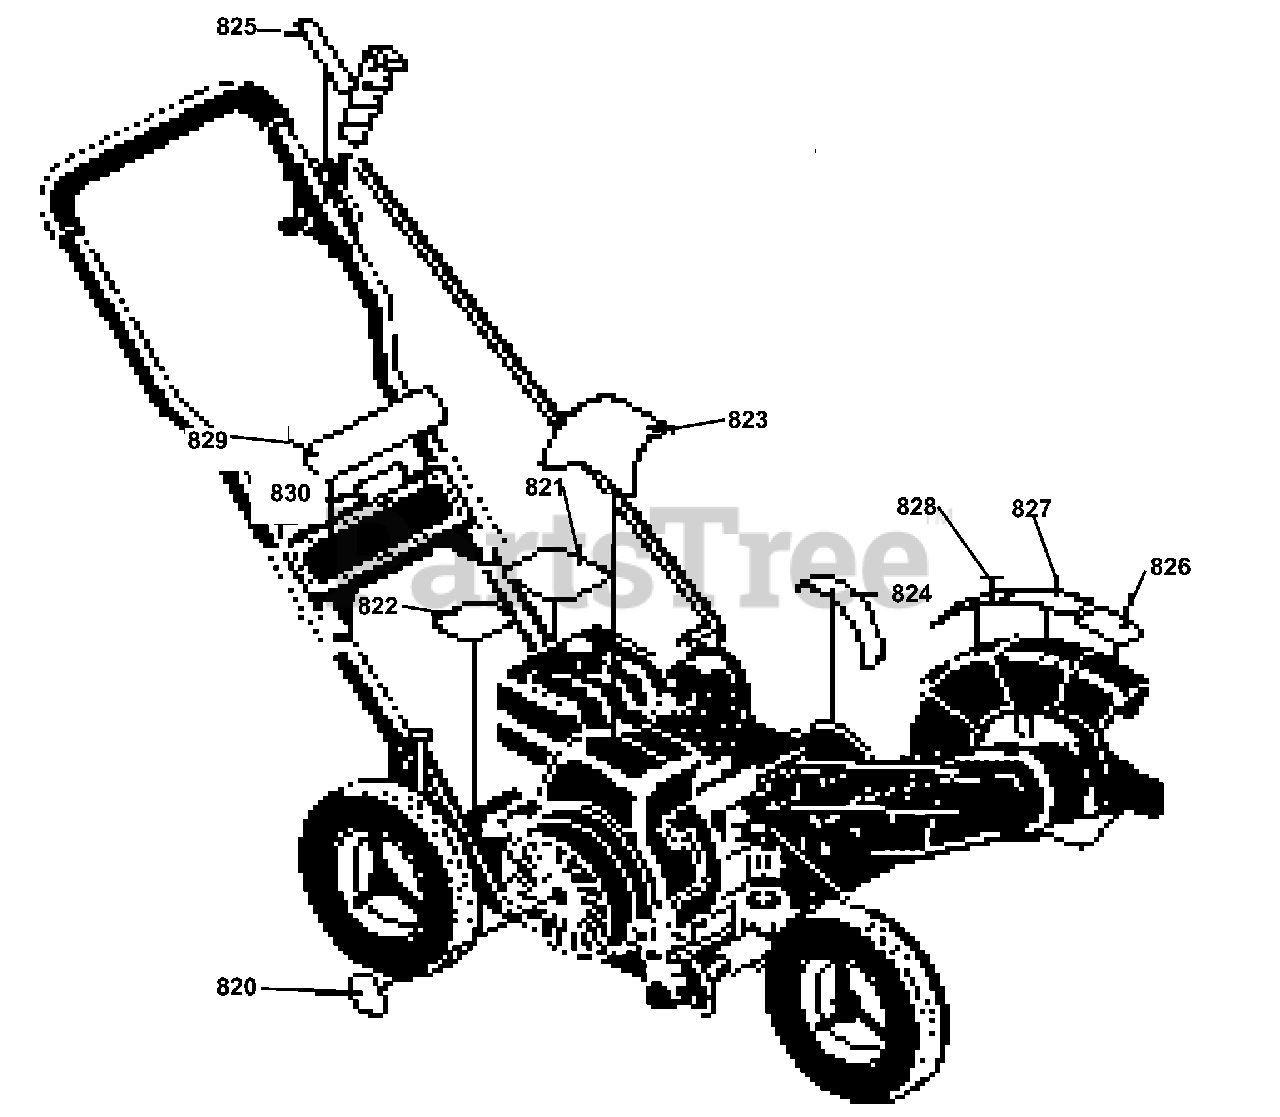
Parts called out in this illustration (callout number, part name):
820	Decal, Recoil Cover
821	Decal, Information Danger
822	Reference Only
823	Decal, Engine
825	Decal, Quadrant Selector
826	Decal, Blade Guard
829	Decal, Panel
830	Decal, Husq. LE359
